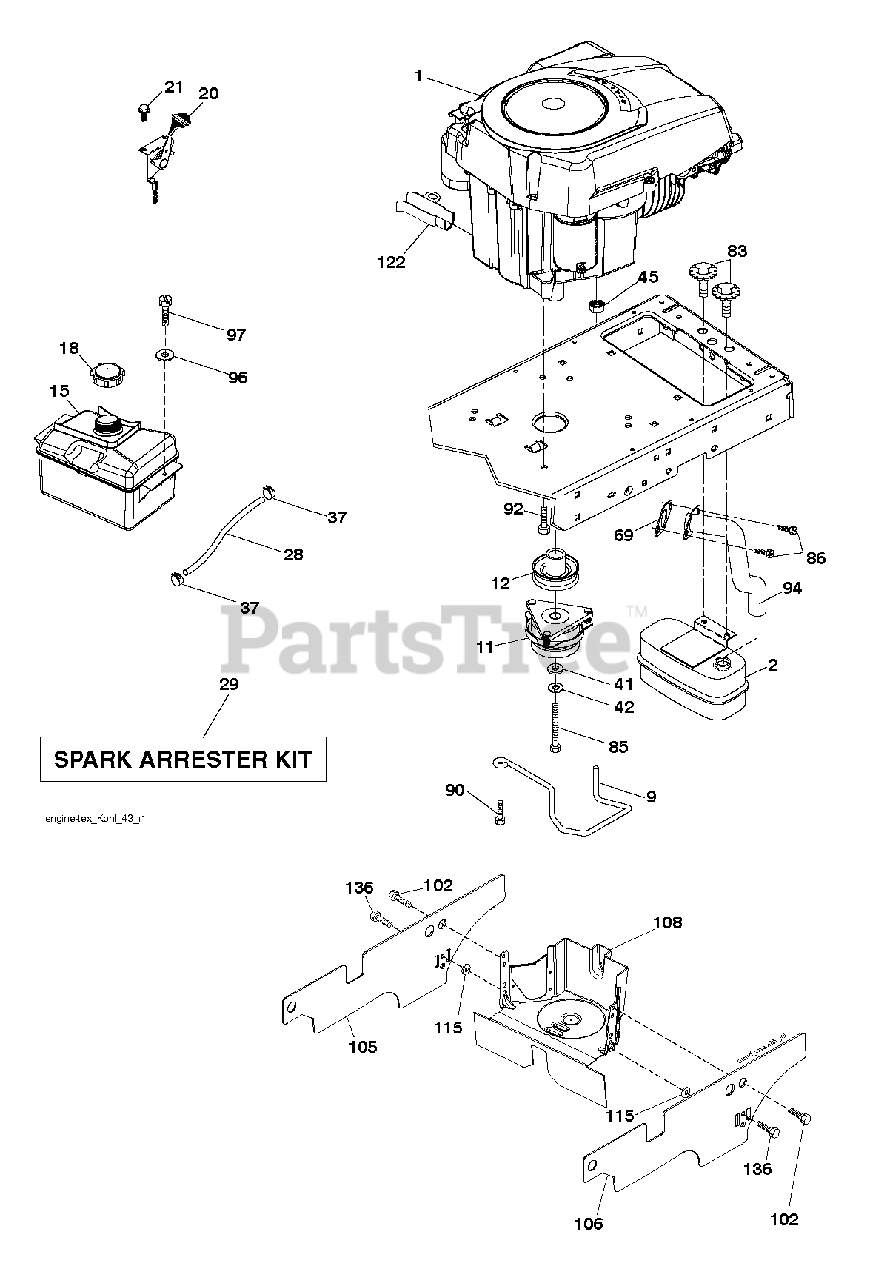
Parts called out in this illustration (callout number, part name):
2	MUFFLER.SINGLE.LRG.BRIGGS.KOHL
9	KEEPER BELT ENGINE
11	RB.CLUTCH.OGURA.4.4.PD
12	PULLEY.ENGINE.TUFFTORQ
15	RP TANK FUEL FRT 1.5 GAL
18	CAP ASM.FUEL.2.25"FR.
20	CONTROL.TH/CK.C.
21	SCREW.#10 X 0.750.BOS
28	LINE.FUEL.20
29	KIT.SPARK ARRESTOR 794945 B&S
37	HOSE CLAMP
42	LOCKWASHER
45	NUT
69	REPL BY 532 27 22-93
83	BOLT, 5/16-18 X 1 3/4
85	BOLT HEX 7/16-20X4-1/4"
86	SCREW.SOCKET HD.5/16-1
90	SCREW 3/8-16X1
92	SCREW 3/8-16X1
94	TUBE.EXHAUST.KOHLER.COURAGE
97	SCREW HEXWSHR 1/4-20X3/4
102	SCREW
105	SHIELD.SIDE.LH.3842"TEX FRENCH
106	SHIELD.SIDE.RH.3842"TEX FRENCH
108	ENGINE COVER
115	PALNUT 1/4
122	EXTENSION DRAIN OIL
136	SCREW.1/4-20X5/8
